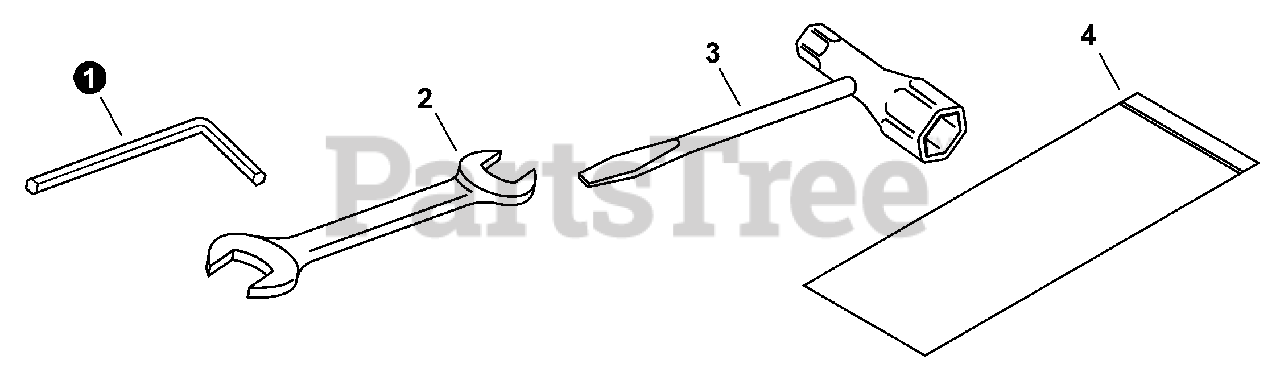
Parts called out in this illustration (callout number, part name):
1	WRENCH, ALLEN 3MM
2	SPANNER 8×10
3	T-WRENCH 16×13
4	BAG, TOOL
